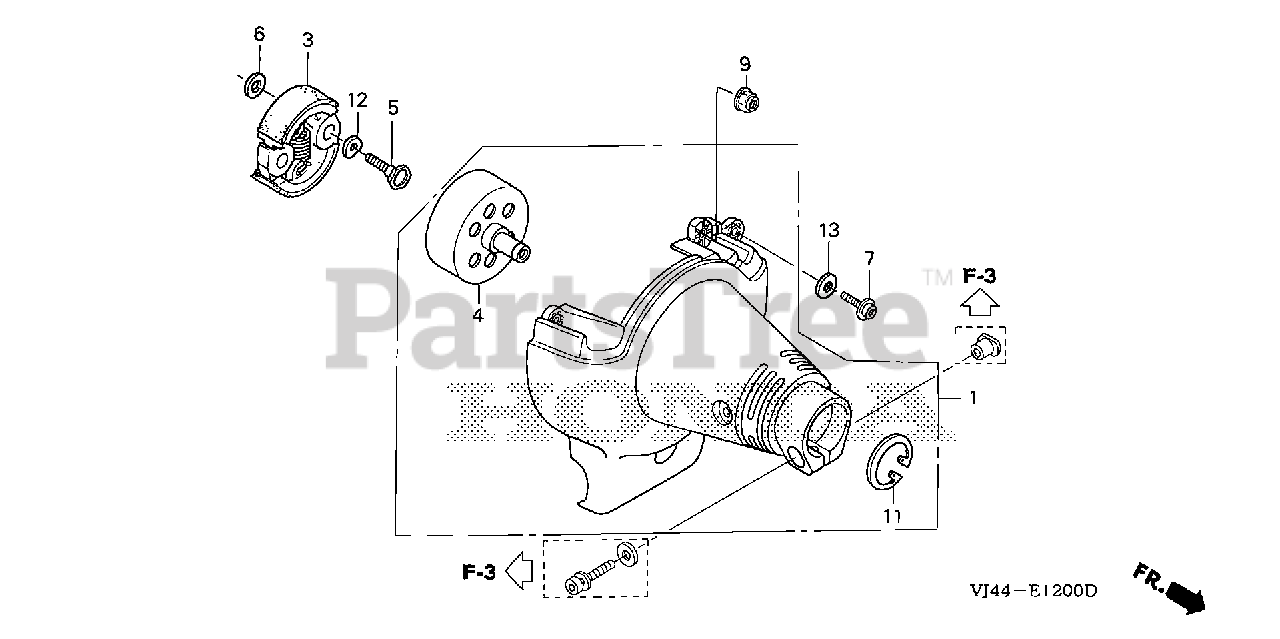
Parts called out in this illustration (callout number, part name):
1	COVER ASSY., FAN
3	CLUTCH ASSY.
4	CLUTCH OUTER
5	BOLT, CLUTCH (6MM)
6	WASHER, CLUTCH (6X15)
7	BOLT, SOCKET (5X20)
9	NUT, SPECIAL (4MM)
11	CIRCLIP (OUTER) (10MM)
12	WASHER, WAVE (8MM)
13	WASHER, PLAIN (5MM)
